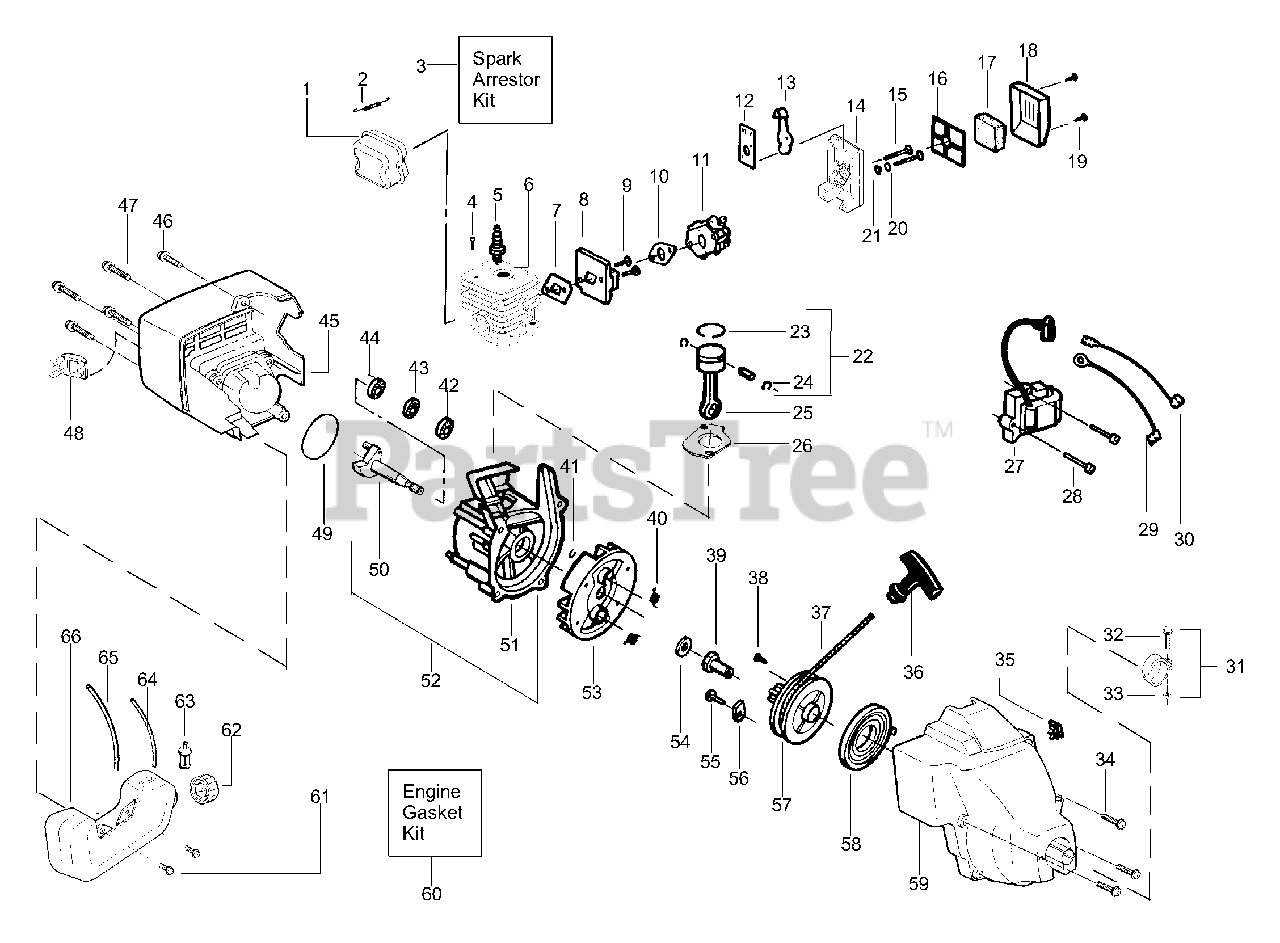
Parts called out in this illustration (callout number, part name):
1	Kit-Muffler S.A.
2	Muffler Spring
3	Kit-Spark Arrestor
4	Screw-Cylinder
5	Spark Plug (RCJ 6Y)
6	Kit-Cylinder
7	Gasket-Cyl./Carb.(kit)
8	Carb. Adaptor
10	Gasket-Carb.(kit)
11	Kit-Carburetor Ass'y
12	Choke Plate Mounting
13	Choke Shutter
16	Plate-Filter Support
17	Air Filter Foam
18	Air Filter Cover
20	Spacer-Choke
22	Kit-Piston
23	Piston Ring
24	Piston Pin Retainer
25	Connecting Rod Ass'y.
26	Gasket-Cylinder(kit)
27	Ignition Module
29	Assy-Ground Wire
30	Assy-Leadwire
31	Nose Cone Clamp Ass'y.
32	Screw-Nose Cone
33	Nut-Nose Cone
34	Screw
35	Kit-On/Off Switch
36	Starter Handle
37	Kit-Rope
39	Drive Coupling
40	Starter Dog Spring
41	Retain. Ring-C'shaft
42	Outer Bearing
43	Kit-C'case Seal
44	Inner Bearing
45	Assy.-Fan Hsg/Shroud
47	Screw
48	Guard-Muffler
49	O-Ring-C'case(kit)
50	Assy-Crankshaft
51	Kit-Crankcase Ass'y.
52	C'case & C'shaft Assy.
53	Flywheel Ass'y.
54	Washer-Flat
56	Retainer-Can
57	Starter Pulley Kit
58	Starter Spring
59	Kit-Fan Hsg/Shroud
60	Kit-Engine Gasket
61	Retainer
62	Assy-Fuel Cap
63	Assy-Fuel Pickup
64	Kit-Fuel Line (Small)
65	Kit-Fuel Line (Large
66	Assy-Fuel Tank
